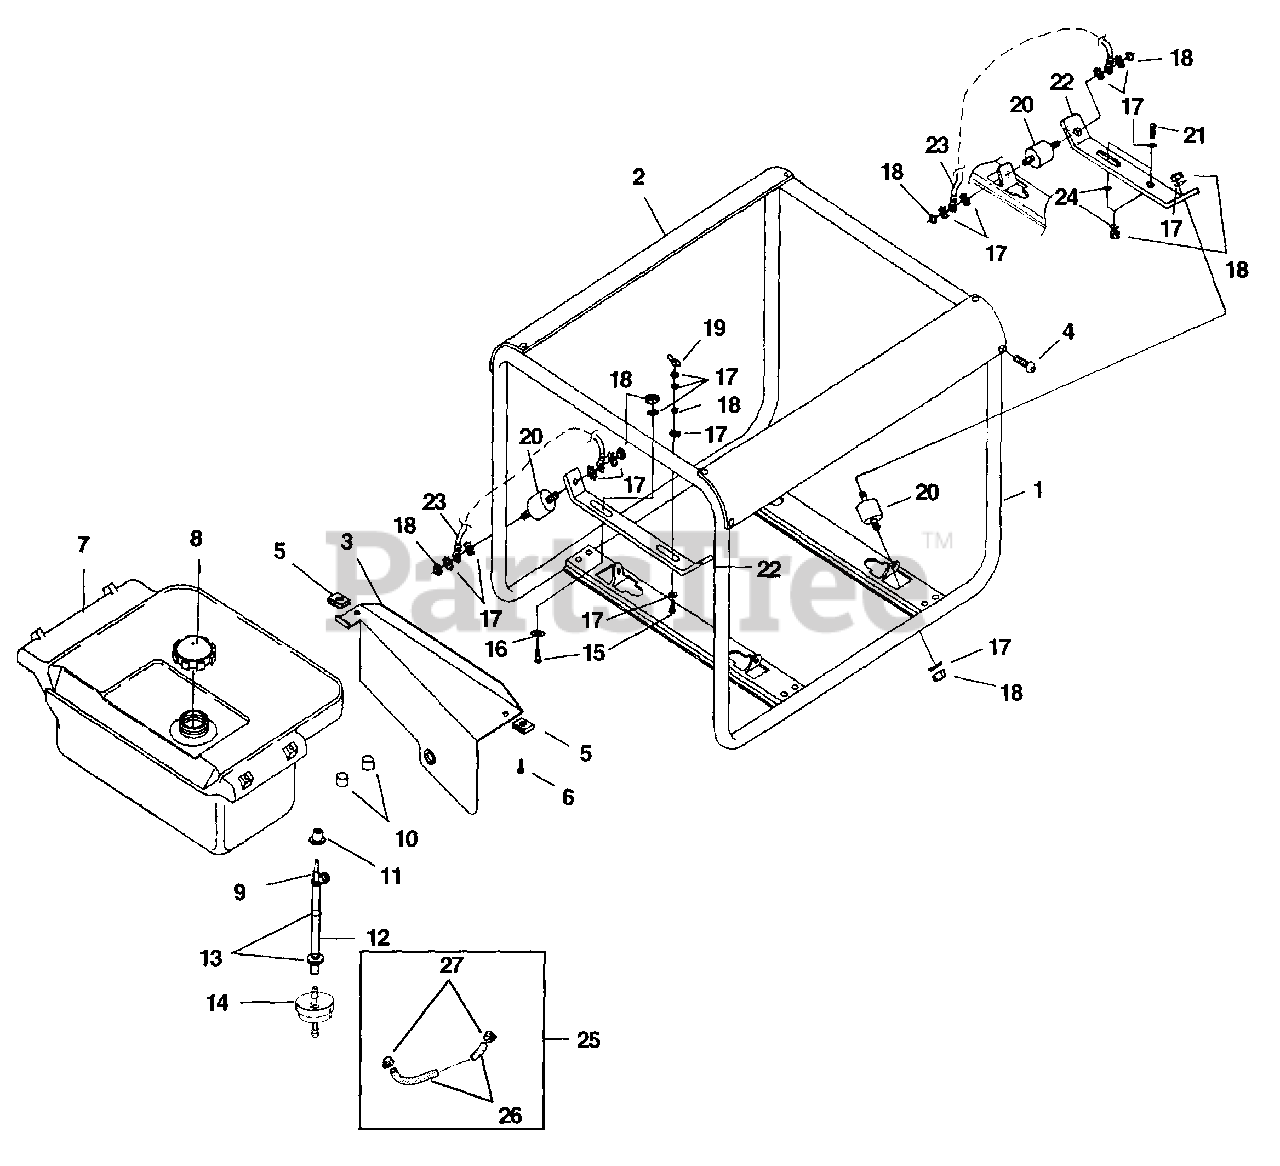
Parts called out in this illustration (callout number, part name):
1	Roll Cage
2	Brace - Tank Support
3	Shield - Fuel Tank
4	Screw - Torx (10-24 X 1/2")
5	Nut - Speed
6	Screw - Pan Hd. (8-32 X 3/8")
7	Fuel Tank (5 Gal.)
8	Cap - Fuel (2 1/4" Dia.)
9	Valve - Fuel
10	Pad - Fuel Tank
11	Bushing
12	Hose Fuel (8")
13	Clip - Hose
14	Fuel Filter
15	Screw - Hex Hd. (5/16-18 X 1 1/4")
16	Washer - Flat
17	Washer - Lock (int.)
18	Nut - Hex (5/16-18)
19	Nut - Wing (5/16-18)
20	Isolator
21	Screw - Hex Hd. (5/16-18 X 3/4")
22	Support - Eng/Gen
23	Ground Strap
24	Washer, Lock -Int - Ext.
25	Fuel pipe
26	Rubber pipe
27	Hose clamp
